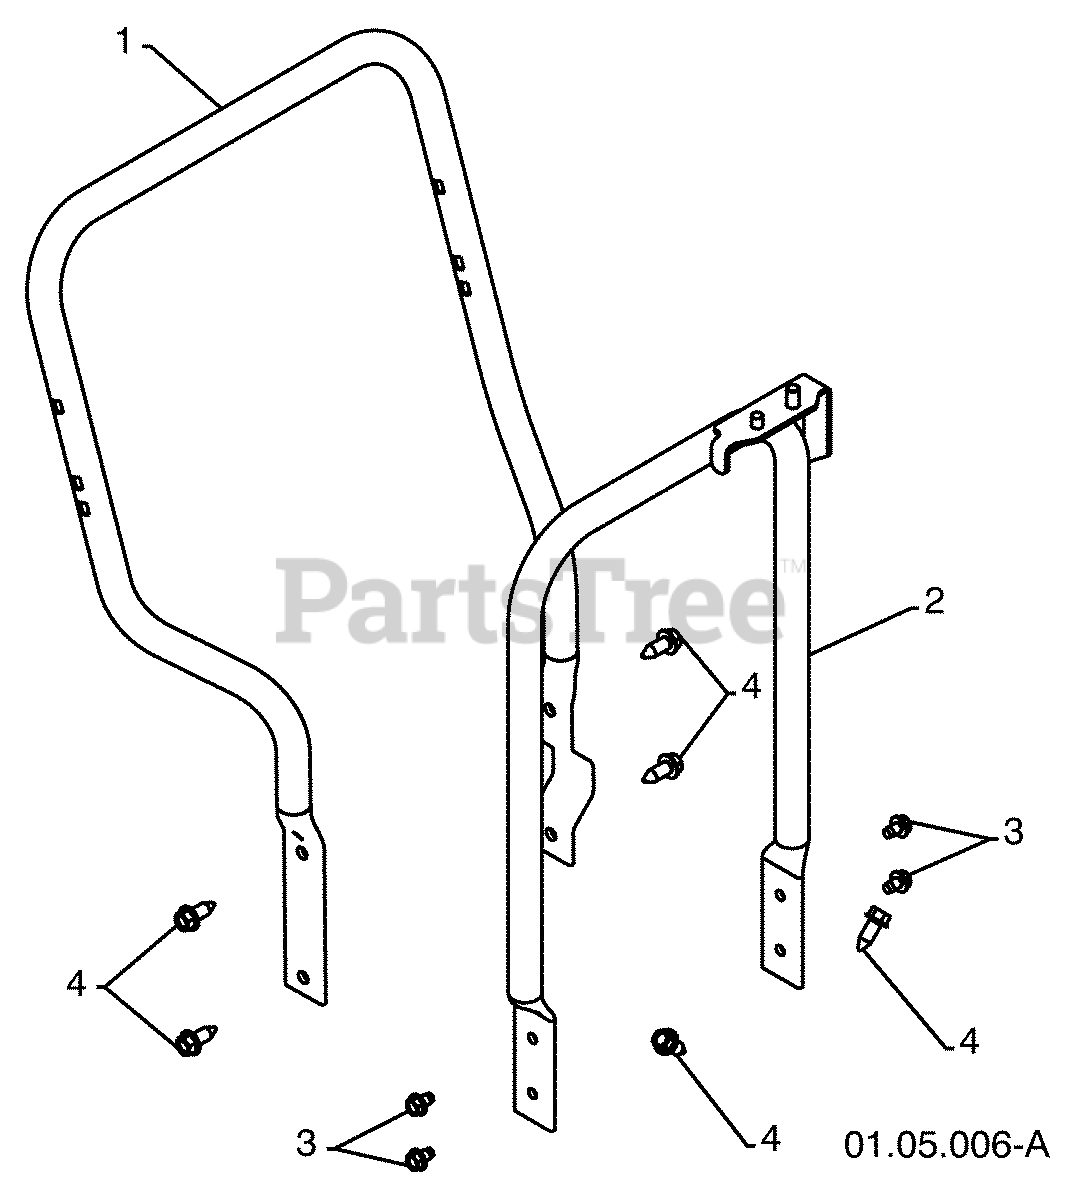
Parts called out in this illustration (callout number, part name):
1	LOWER TUBE GRAY
2	PIVOT SUPPORT
3	BOLT 5/16-18 X .500
4	SCREW 3/8-16 X 1.00
